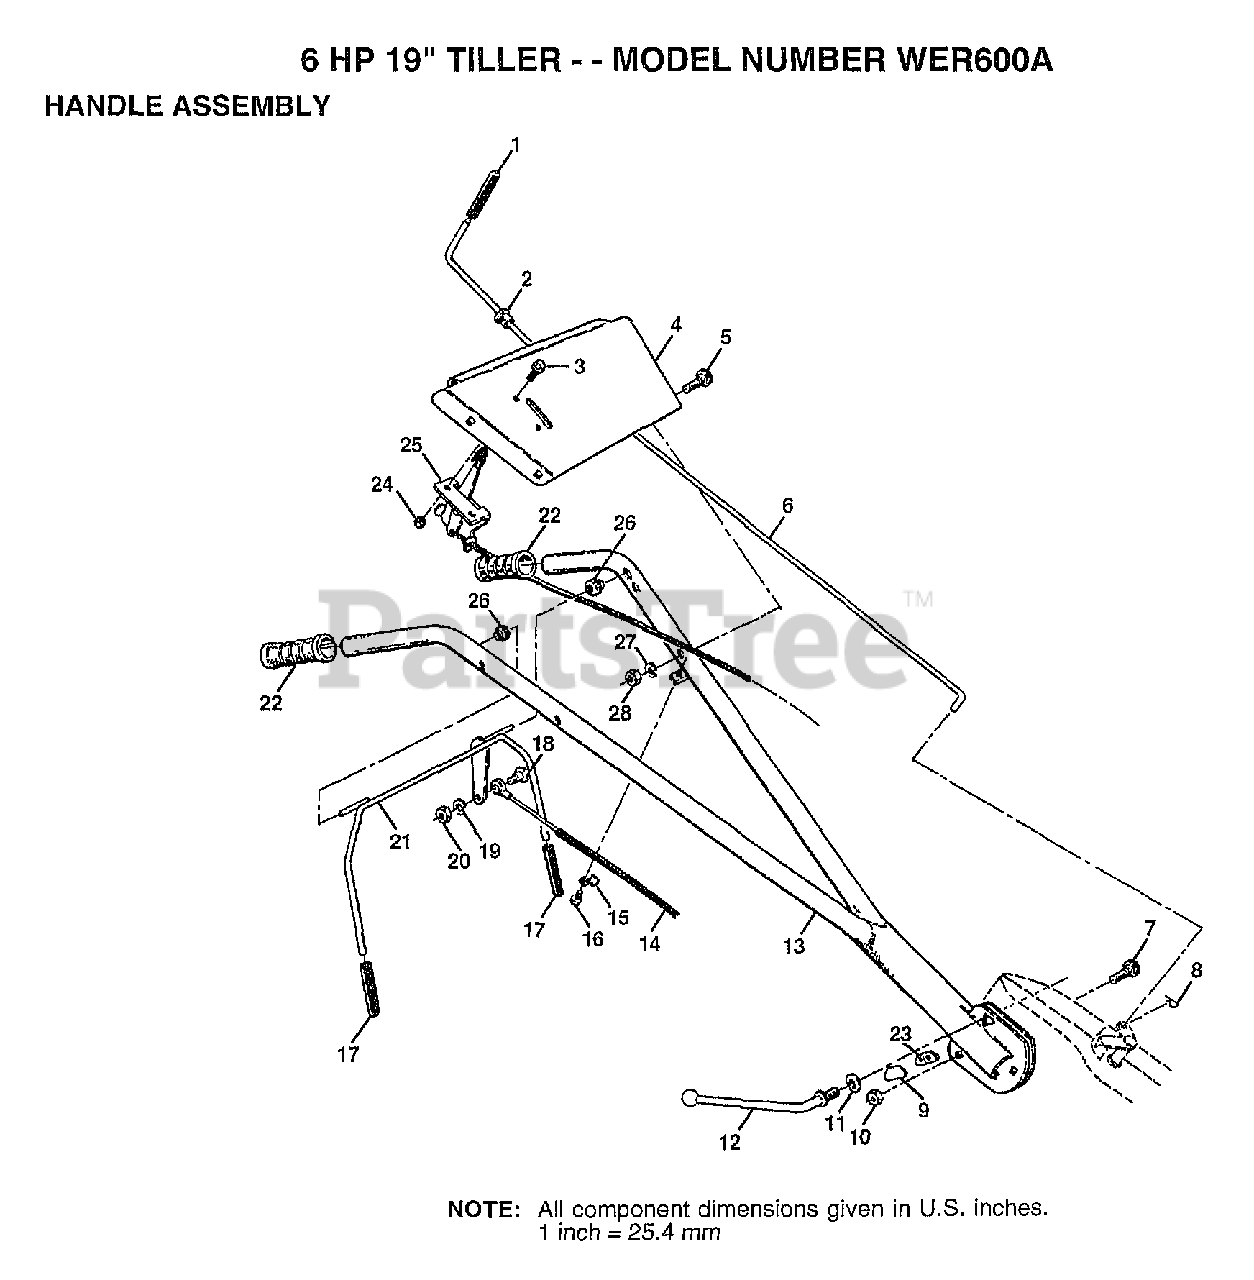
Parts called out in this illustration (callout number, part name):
1	GRIP TI
2	BUSHING
3	SCREW
5	BOLT CARRIAGE CRT
6	ROD SHIFT CRT
8	RETAINER M
9	LOCK CRT
10	LOCKNUT
11	WASHER CRT
12	LEVER LOCK CRT
14	CABLE-CLUTCH CRT
15	CONDIUT CLIP T
17	GRIP BAR CRT
18	SHOULDER BOLT ST
19	LOCKWASHER
21	HANDLE BAR CRT
22	GRIP HDLE NUBBED
23	LOCK.HANDLE
25	CONTROL.TRTL.6HP.
27	LOCKWASHER
28	NUT
